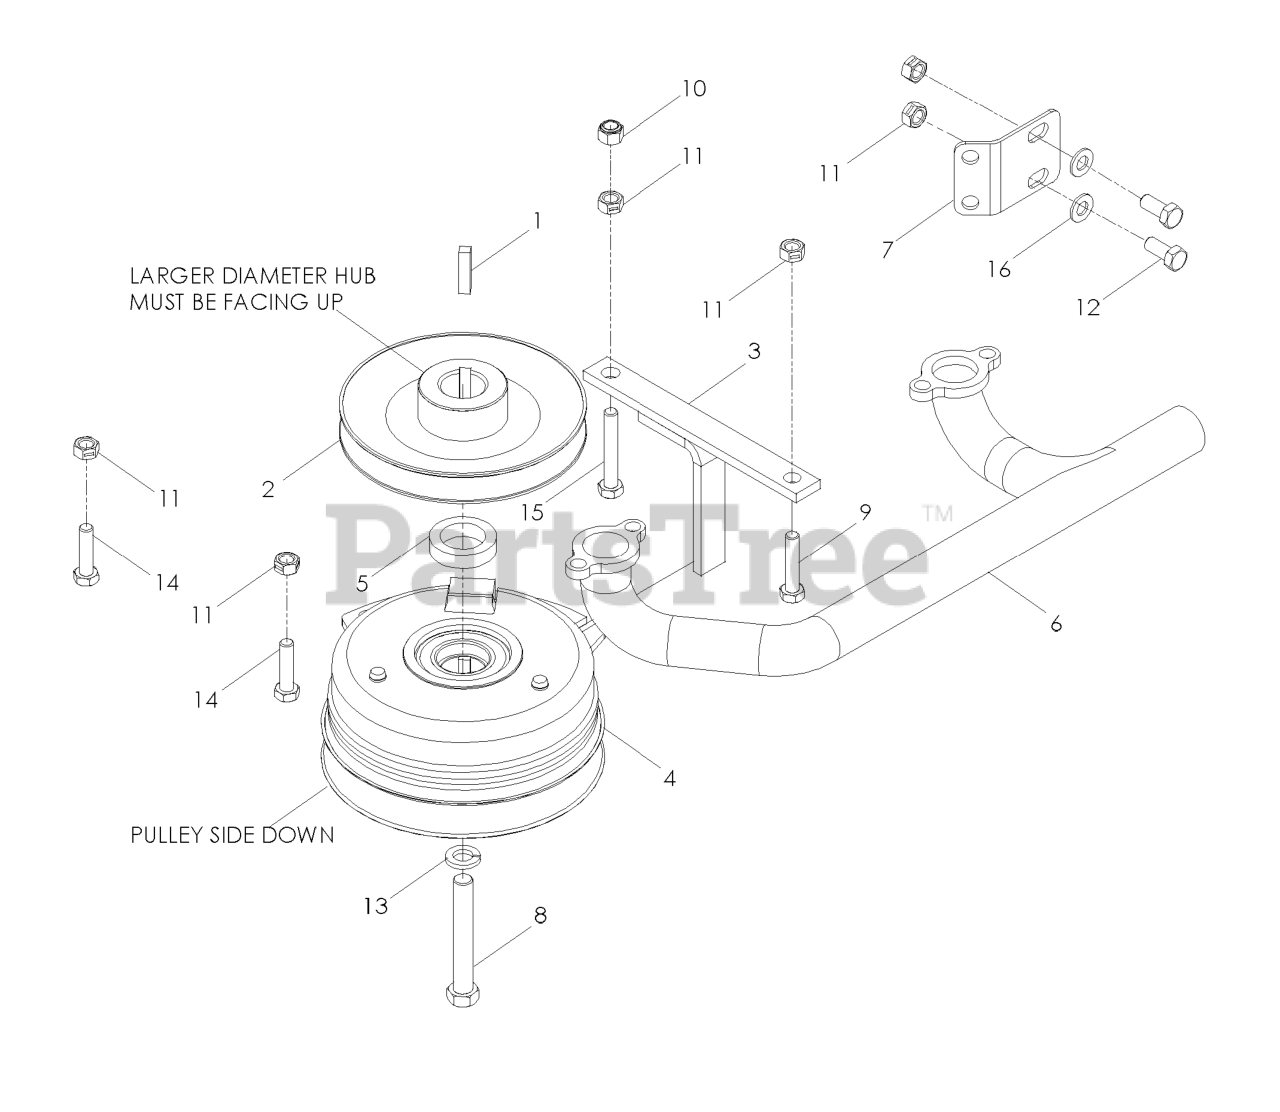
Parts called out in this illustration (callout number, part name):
1	KEY 1/4 SQ X 1 1/8
3	CLUTCH TIE DOWN
4	CLUTCH 125 FT/LB
6	MANIFOLD-EXHAUST, 21HP KAW
7	BRACKET-MUFFLER, BLK
8	HEX SCREW 7/16-20 X 3
9	CAPSCREW 5/16 X 1/1/2 HEX HEAD
10	NUT 5/16 NYLOC
11	NUT 5/16C CENTERLOCK
12	SCREW 5/16C X 1 HEX CAP
13	WASHER 7/16 LOCK
14	HCS 5/16C X 1 1/4
15	HCS 5/16-18X2
16	FLAT WASHER 5/16 SAE
